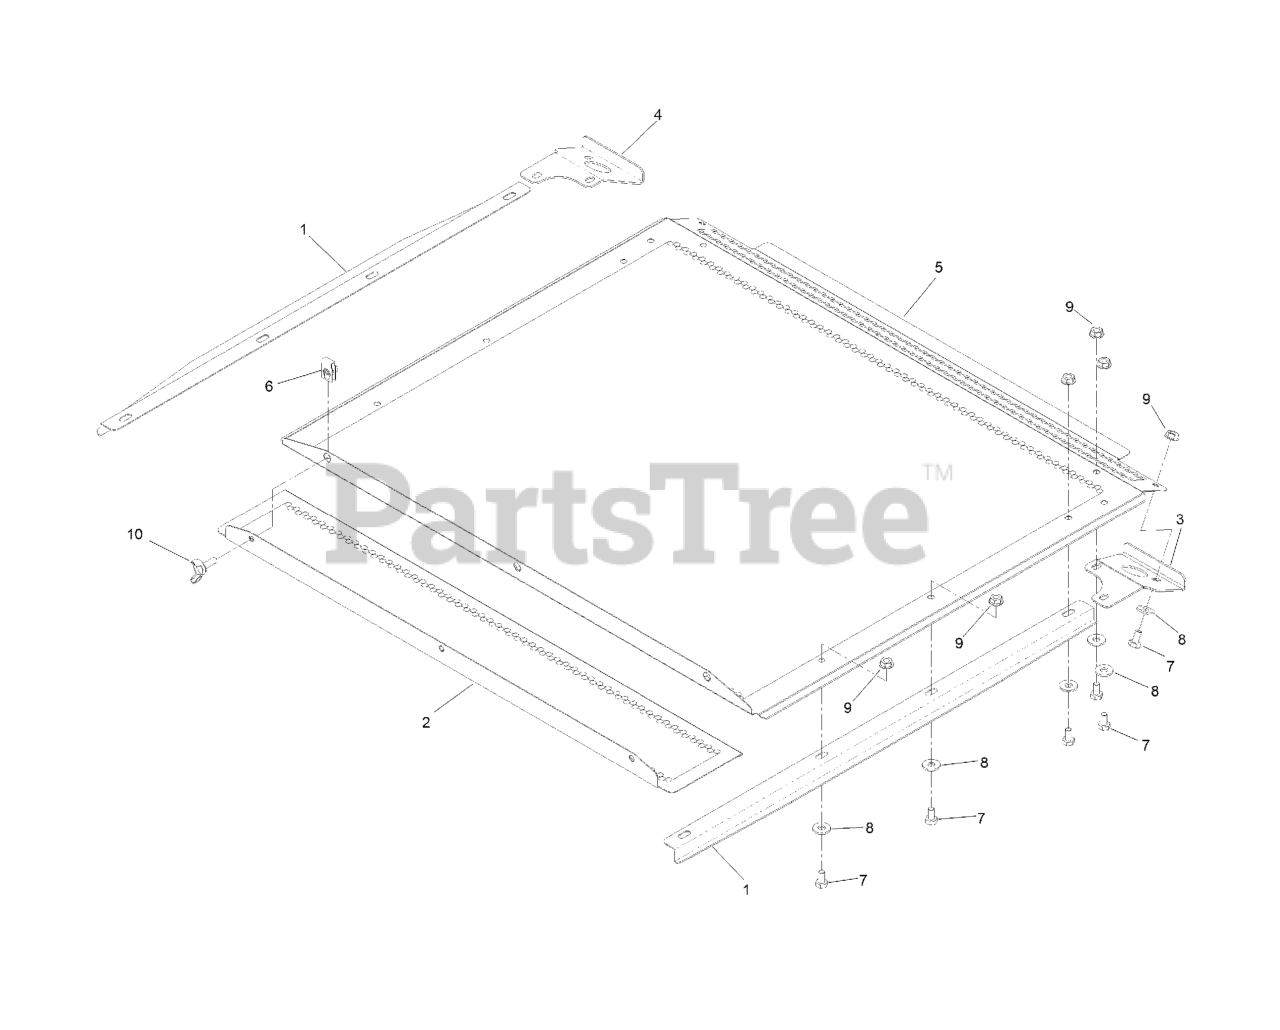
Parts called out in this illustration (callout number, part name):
1	GUIDE-SCREEN
2	PANEL-SCREEN, REMOVABLE
3	HANDLE-SCREEN, LH
4	HANDLE-SCREEN, RH
5	PANEL-SCREEN, HOPPER
7	SCREW-HH
8	WASHER-FLAT
10	SCREW-WING
